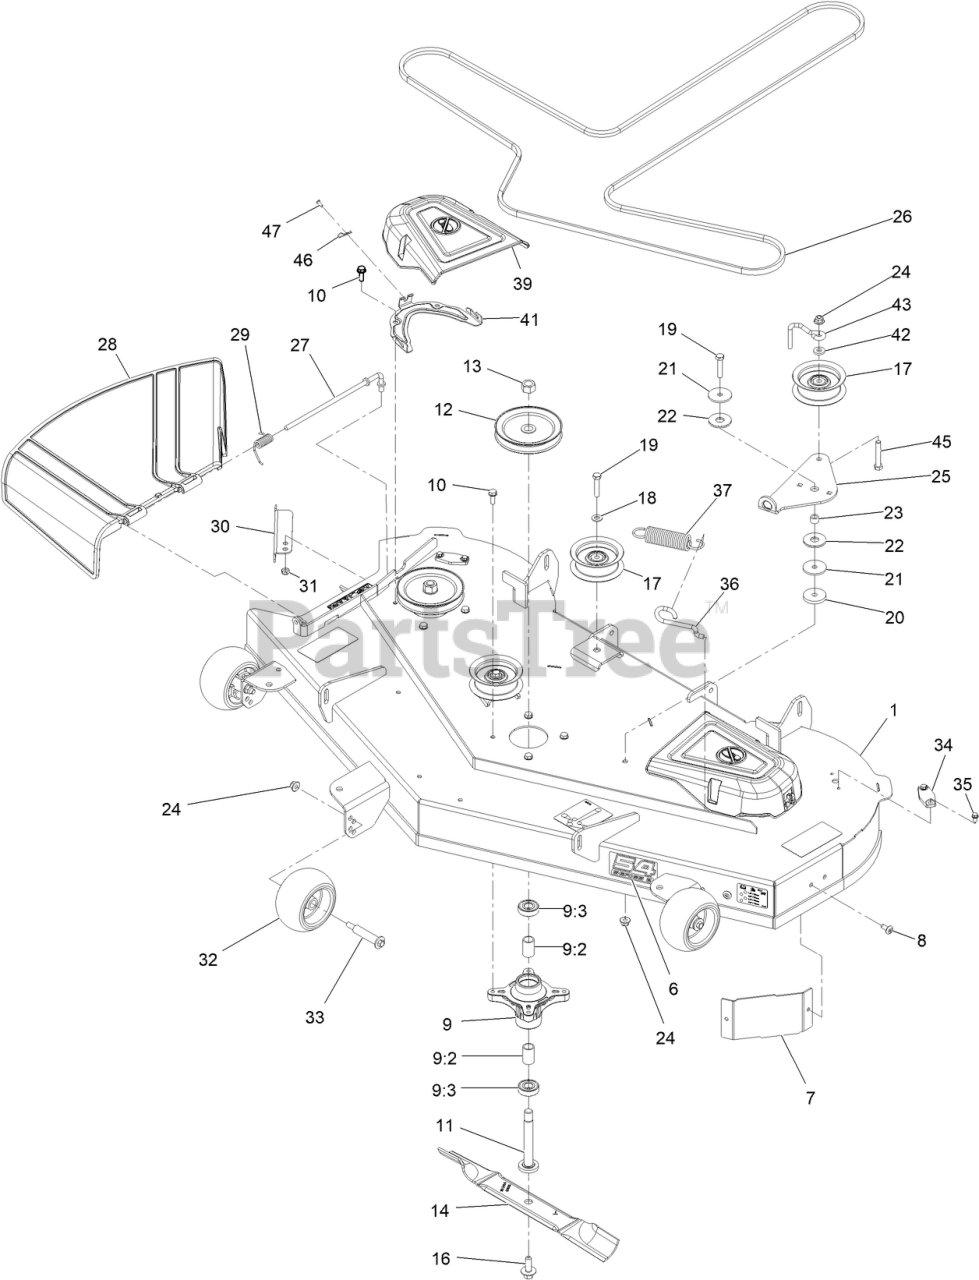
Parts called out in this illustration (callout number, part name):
1	DECK ASM-54 4PT
6	DECAL-54 SERIES 2
7	BAFFLE-CORNER
9	SPINDLE ASM
9:3	BEARING-BALL
10	SCREW-TAPTITE
11	SHAFT-SPINDLE
12	PULLEY ASM
13	NUT-HEX
14	BLADE-HI LIFT
16	Bolt-Blade, Sems
17	PULLEY-IDLER, FLAT
18	WASHER-FLAT
19	SCREW-HH
20	WASHER-PLAIN
21	WASHER-REBOUND
22	WASHER-FRICTION, COMPOSIT
24	NUT-HF, NI
25	Arm-Idler
26	BELT-V
27	ROD-PIVOT
28	DEFLECTOR-DISCHARGE
29	SPRING-TORSION
30	BAFFLE-CUTOFF
32	ROLLER-SCALP, ANTI
33	BOLT-SHOULDER
34	COVER-WASHOUT PORT
35	SCREW-HWH
36	Hook-Return Spring
37	SPRING-EXTENSION
39	COVER-BELT
41	BRACKET-COVER, BELT
42	SPACER-HUB, BLOWER
43	Belt Guide - Idler
45	SCREW-HH
46	PIN-HAIR
